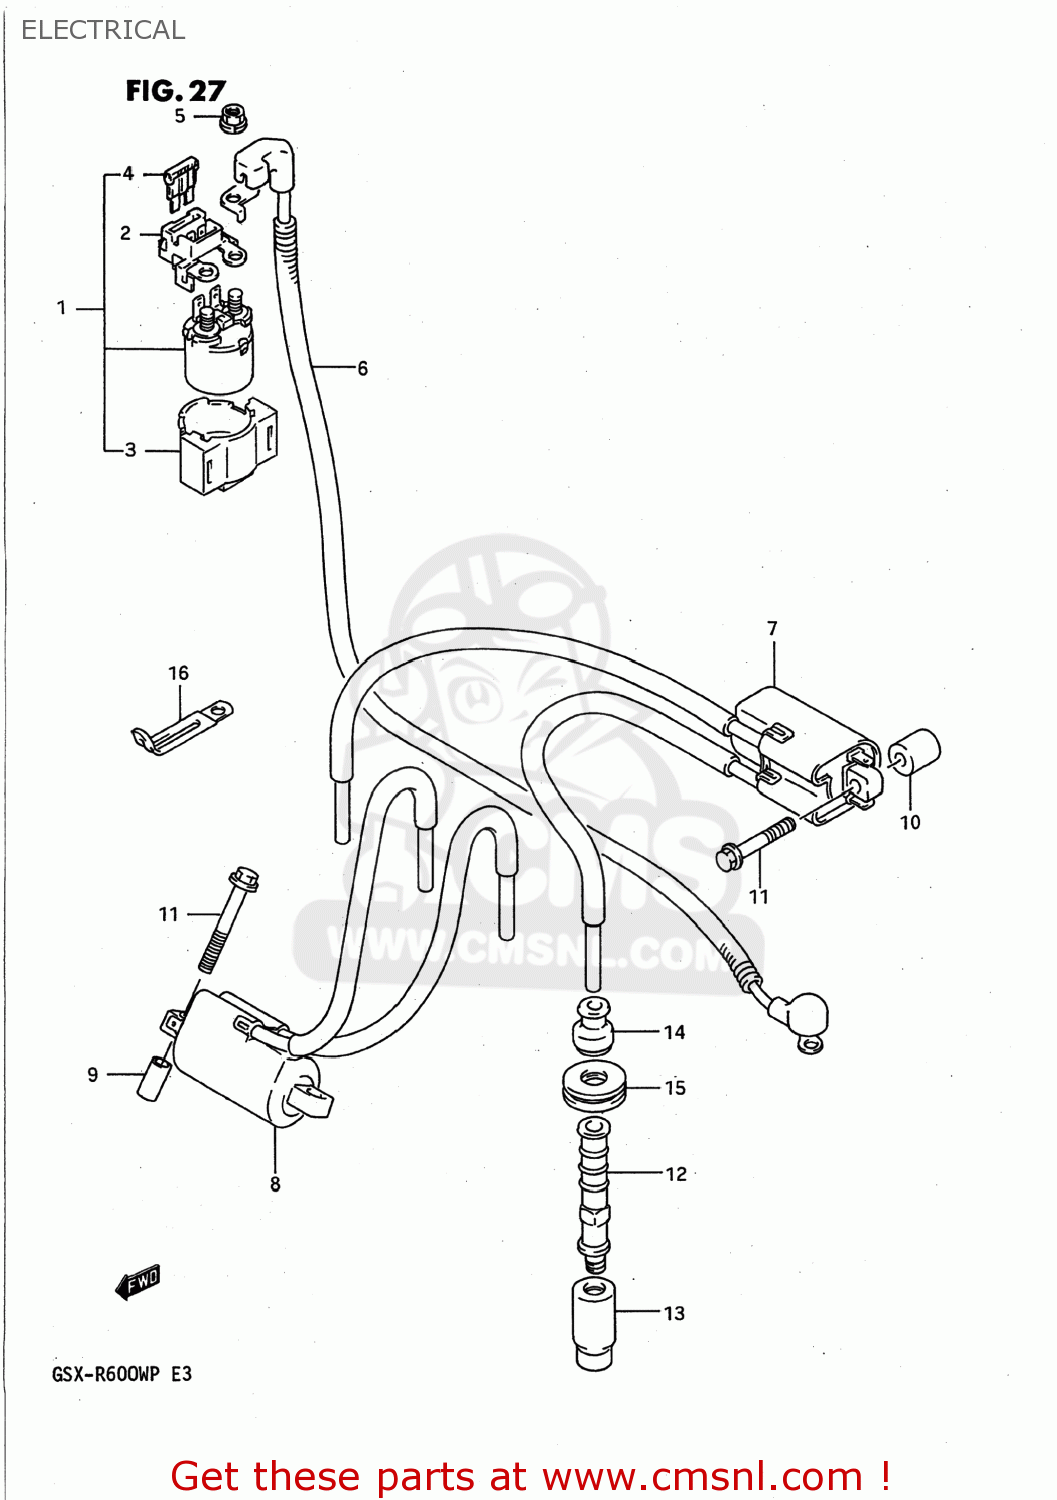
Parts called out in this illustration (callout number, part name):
1	RELAY ASSY,STARTING MOTOR
2	TERMINAL,RELAY
3	BRACKET,STARTING MOTOR RELAY
4	FUSE (30A)
5	NUT
6	WIRE,STARTER MOTOR
7	COIL ASSY,IGNITION
8	COIL ASSY,IGNITION
9	SPACER
10	SPACER,IGNITION COIL 1
11	BOLT
12	CAP,SPARK PLUG
13	SEAL,SPARK PLUG
14	SEAL,HIGH TENSION CORD
15	COVER,SPARK PLUG CAP
16	CLAMP
